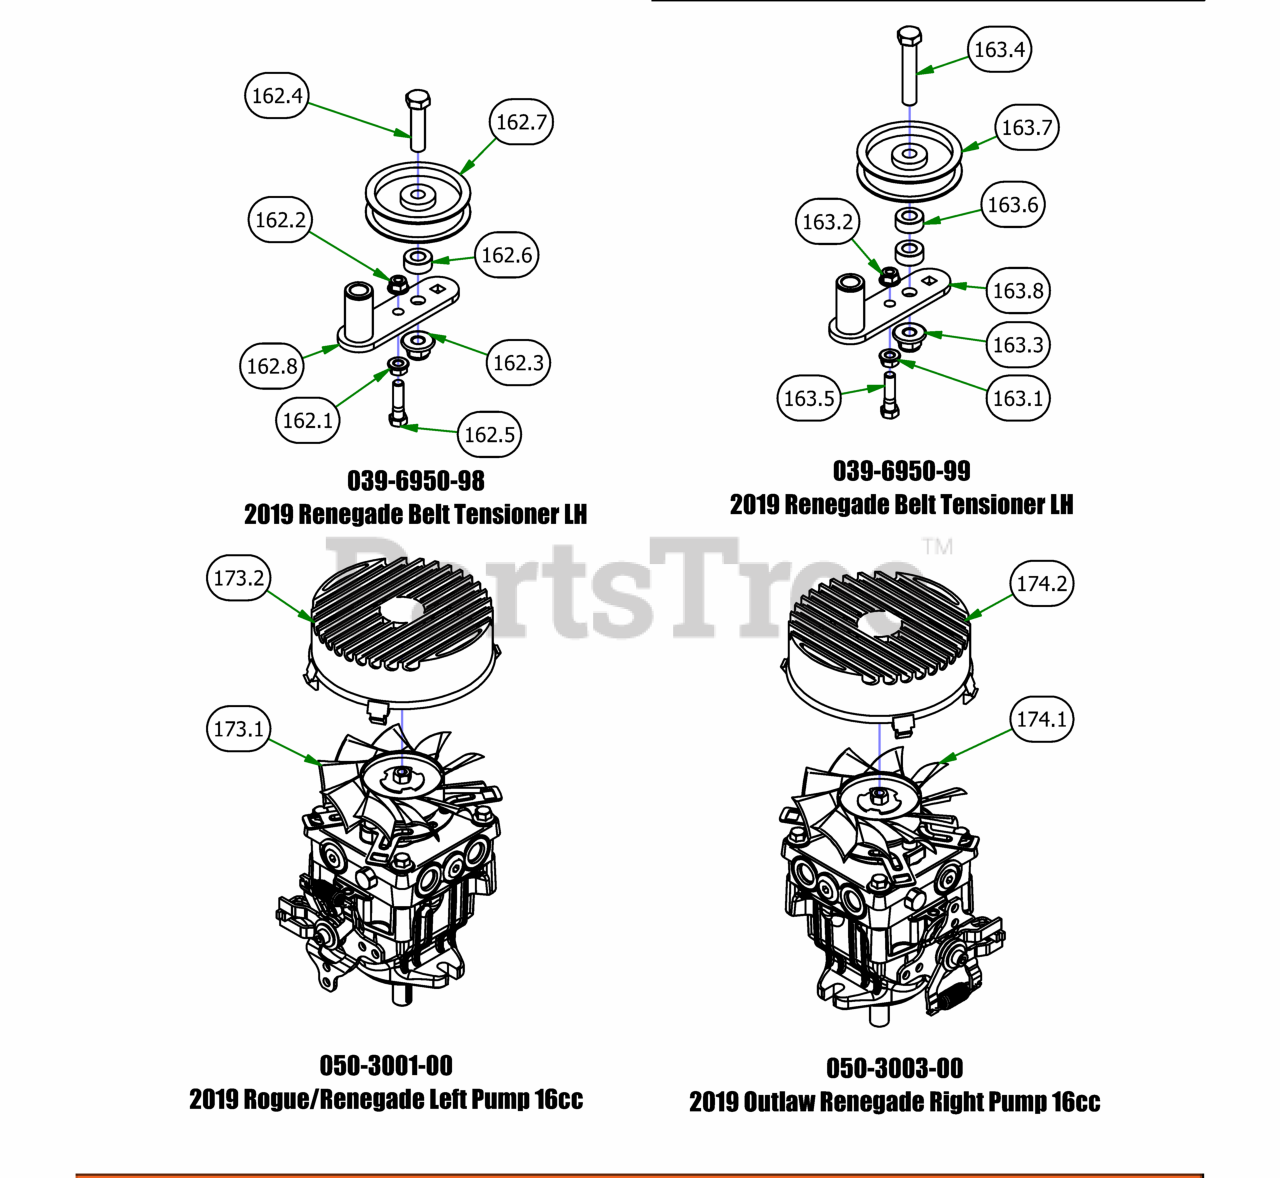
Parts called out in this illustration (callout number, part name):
162.1	3/8" Flange Nut
162.2	3/8" Nylock Flange Nut
162.3	1/2-13 Nylon Flange Nut
162.4	1/2-13x2 Grade 8 Hex Bolt
162.5	3/8" x 1 1/2" Hex Bolt
162.6	1/2 Solid Shaft Collar (W/1 Set Screw) Zinc
162.7	3.25 Flat Idler Pulley
162.8	Horizontal Idler Arm with Bushings
163.1	3/8" Flange Nut
163.2	3/8" Nylock Flange Nut
163.3	1/2-13 Nylon Flange Nut
163.4	1/2" x 2 3/4" Hex Bolt
163.5	3/8" x 1 1/2" Hex Bolt
163.6	1/2 Solid Shaft Collar (W/1 Set Screw) Zinc
163.7	3.25 Flat Idler Pulley
163.8	Horizontal Idler Arm with Bushings
173.1	Hydraulic Fan
173.2	Fan Guard 6" Fits wheel Motor Pumps
174.1	Hydraulic Fan
174.2	Fan Guard 6" Fits wheel Motor Pumps
